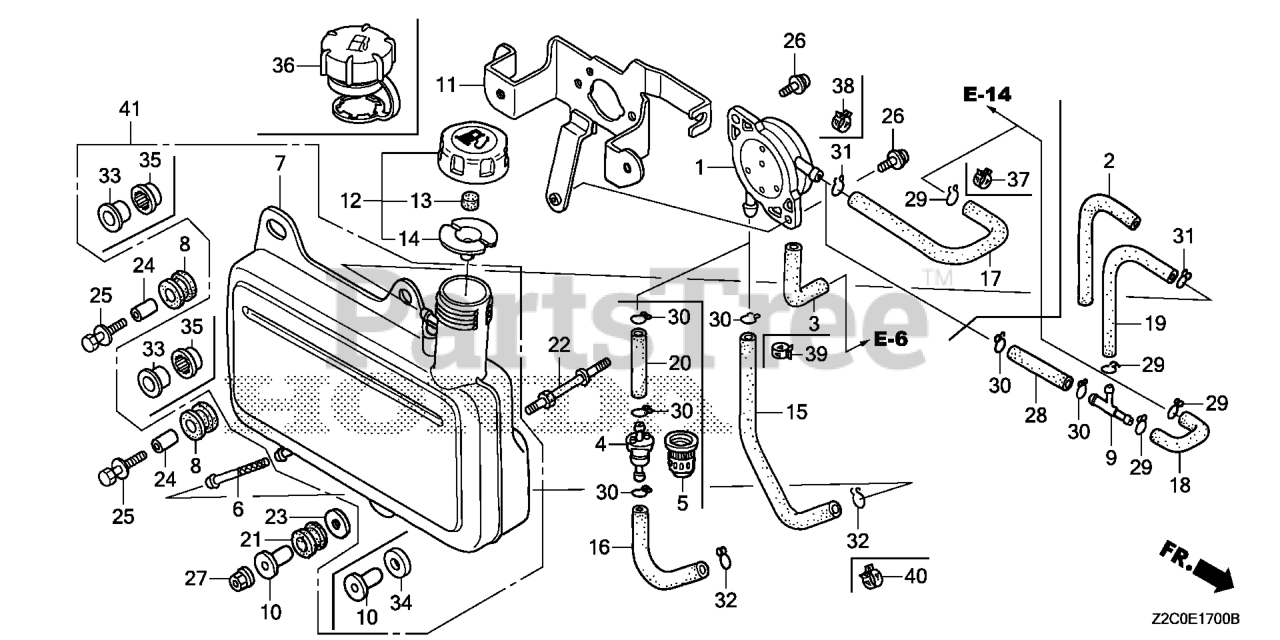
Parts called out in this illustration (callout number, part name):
1	PUMP ASSY., FUEL (MSDS)
3	TUBE, DIAPHRAGM
6	FILTER, FUEL
7	TANK, FUEL
10	COLLAR, FUEL TANK SETTING
11	STAY A, FUEL TANK
15	TUBE, FUEL TANK (FKM)
17	TUBE, FUEL (FKM)
22	BOLT, FUEL TANK STUD (H=30MM)
23	WASHER (6MM)
25	BOLT-WASHER (6X25)
26	SCREW-WASHER (5X14)
27	NUT, FLANGE (6MM)
33	COLLAR, TANK SET
34	RUBBER A, TANK MOUNTING
35	RUBBER B, TANK MOUNTING
36	CAP ASSY., FUEL TANK
37	CLIP, TUBE (D8)
38	CLIP, TUBE (D8.5)
39	CLAMP, TUBE (D10)
40	CLAMP, TUBE (D12)
